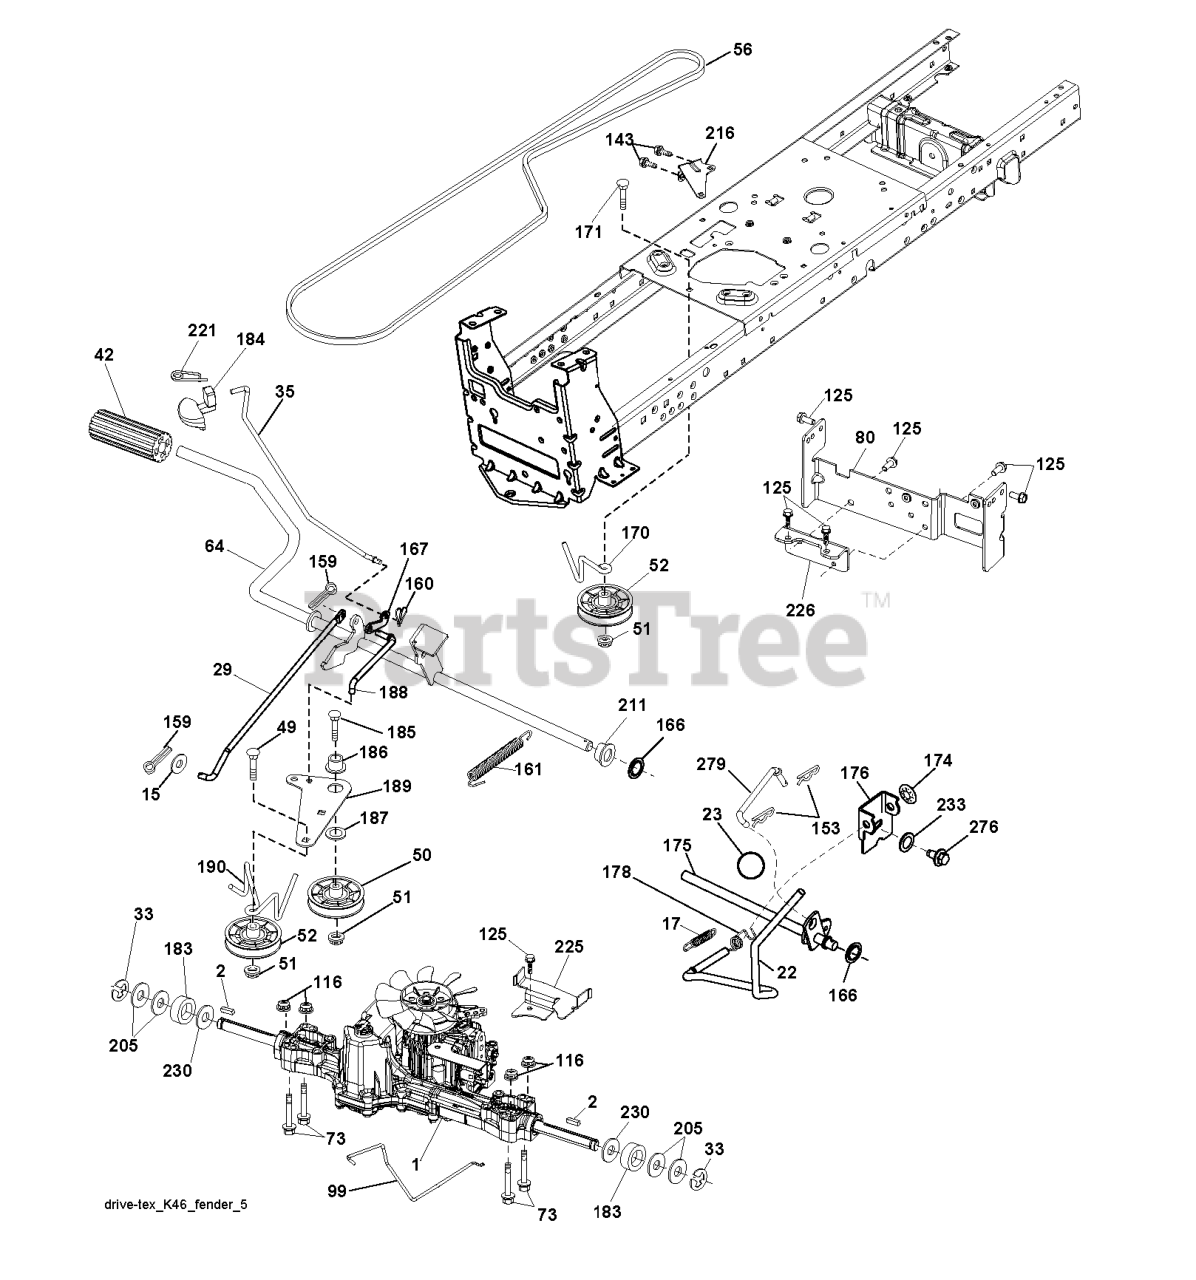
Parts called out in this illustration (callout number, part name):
2	SQUARE KEY
15	WASHER
17	SPRING.BRAKE.K46.GREEN
22	ROD.SHIFT.FENDER.TLT.2006
23	KNOB.DUCKHEAD.1/2
29	ROD.BRAKE.K46
35	ROD.CNTRL.PARK.PREDATOR.LT.TEX
42	PEDAL COVER T
50	IDLER.FLAT.910.OFFSET
51	NUT LOCK FLG 3/8-16 UNC
52	IDLER.V-GROOVE.910.OFFSET
56	V-BELT.MOWER.92.40.42/K46
64	SHAFT.ASM.PEDAL.BRAKE.
73	BOLT HEX 5/16-18 GR 5
80	STRAP TORQUE
99	ROD.SPRING.BYPASS.K46.LT.Z
116	NUT LOCK HEX FLANGE 5/16-18
125	SCREW
143	Screw 5/16-18 x 1/2 Hex, Self Tapping 5/16-18 x 1/2
153	RETAINER M
159	COTTER PIN
160	RETAINER CLIP
161	SPRING, RETURN LT
166	NUT.PUSH.625
167	LATCH.BRAKE.SPRING
170	KEEPER.V-IDLER.CENTER.
174	NUT.PUSH.500.2006
175	SHAFT ASM SHIFT
176	ARM.CLEVIS.ROD.SHIFT
178	SPRING.SHIFT.GT2006
183	SPACER AXLE
184	HANDLE PARKING BRAKE
186	SPACER.RETAINER
187	WASHER 12/32X2X10GA
188	RP.LINK.CLUTCH.GROUND.DRIVE
189	BELLCRANK.GROUND.DRIVE.TEX.
190	KEEPER.BELLCRANK.DRIVE
211	BUSHING.SHAFT.BRAKE.HAND
216	BRACKET.PULLEY.IDLER.W/TEX
221	RETAINER.SPRING.CLIP.H
225	KEEPER.BELT.TRANSAXLE.K46
226	BRACKET.MOUNT.TORQUE.K46.TLT
230	WASHER.HARDENED
233	WASHER SERRATED
276	BOLT FIN HEX 7/16-14 X 1
279	LINK.SHIFT.T/A.K46.FEND.TX
